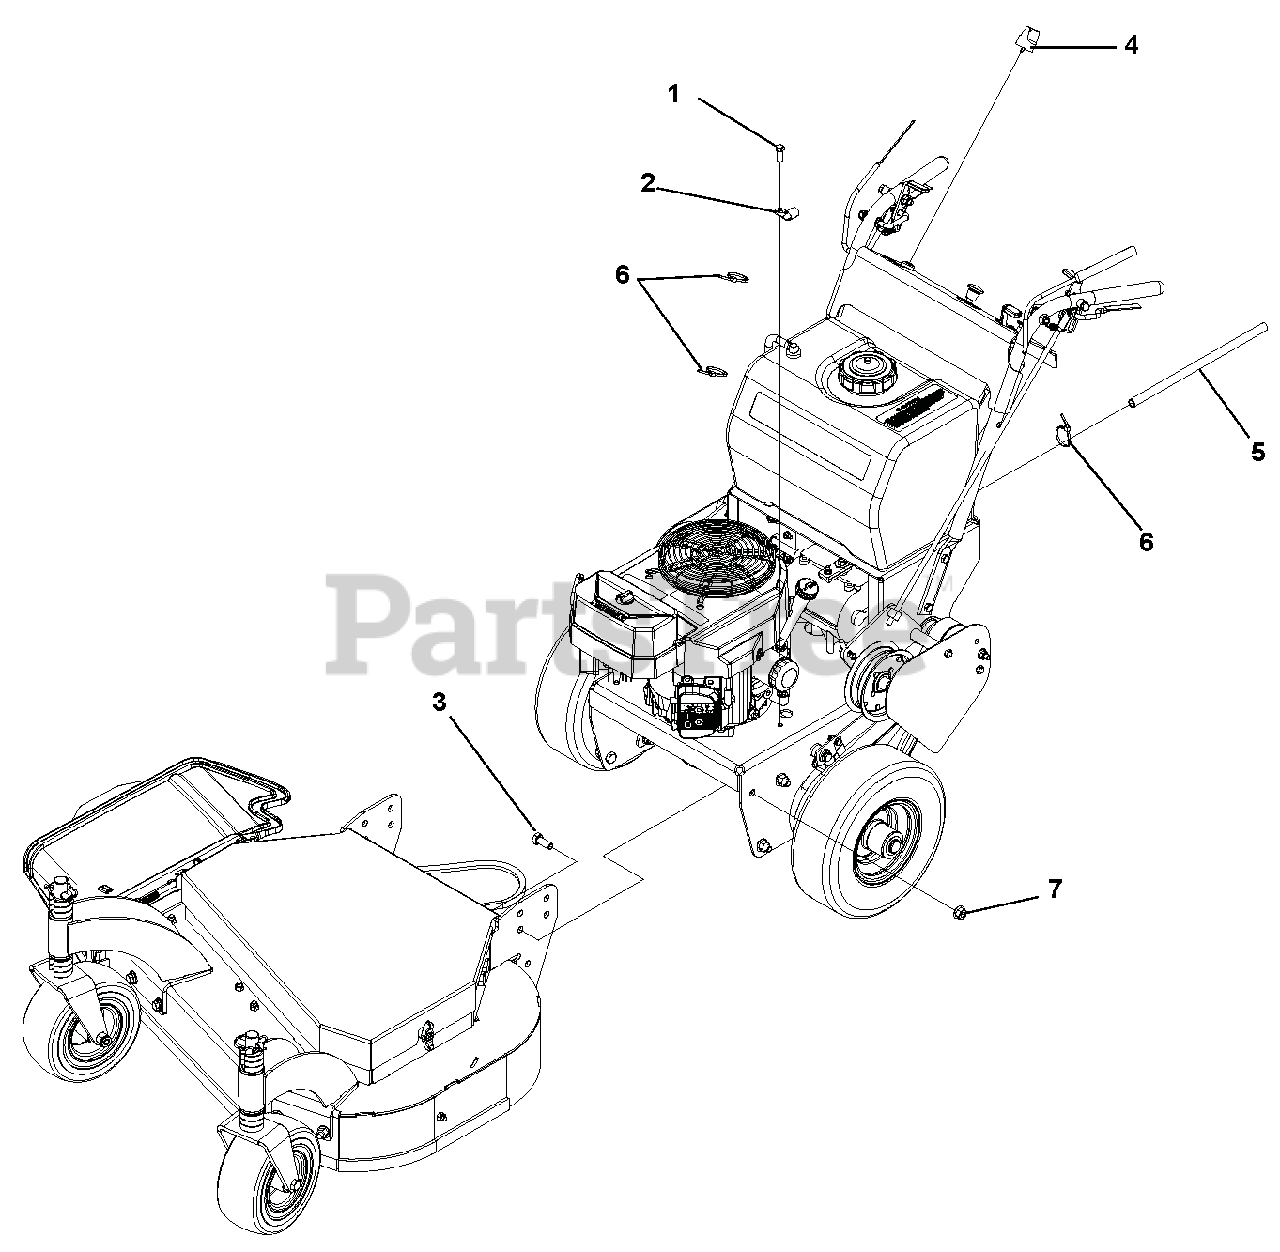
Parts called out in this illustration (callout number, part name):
1	@SCR-TAP .38-16X.50 HWH TR YWZ
3	BOLT, 1/2-13X1.25 HEX 5 Y
4	KEY W/ SHIELD
5	TUBE,OIL DRAIN 14" CLEAR VINYL
6	CABLE TIE, .15 X 8.50
7	@NUT-LK-NYL-FLG .50-13 YWZC
